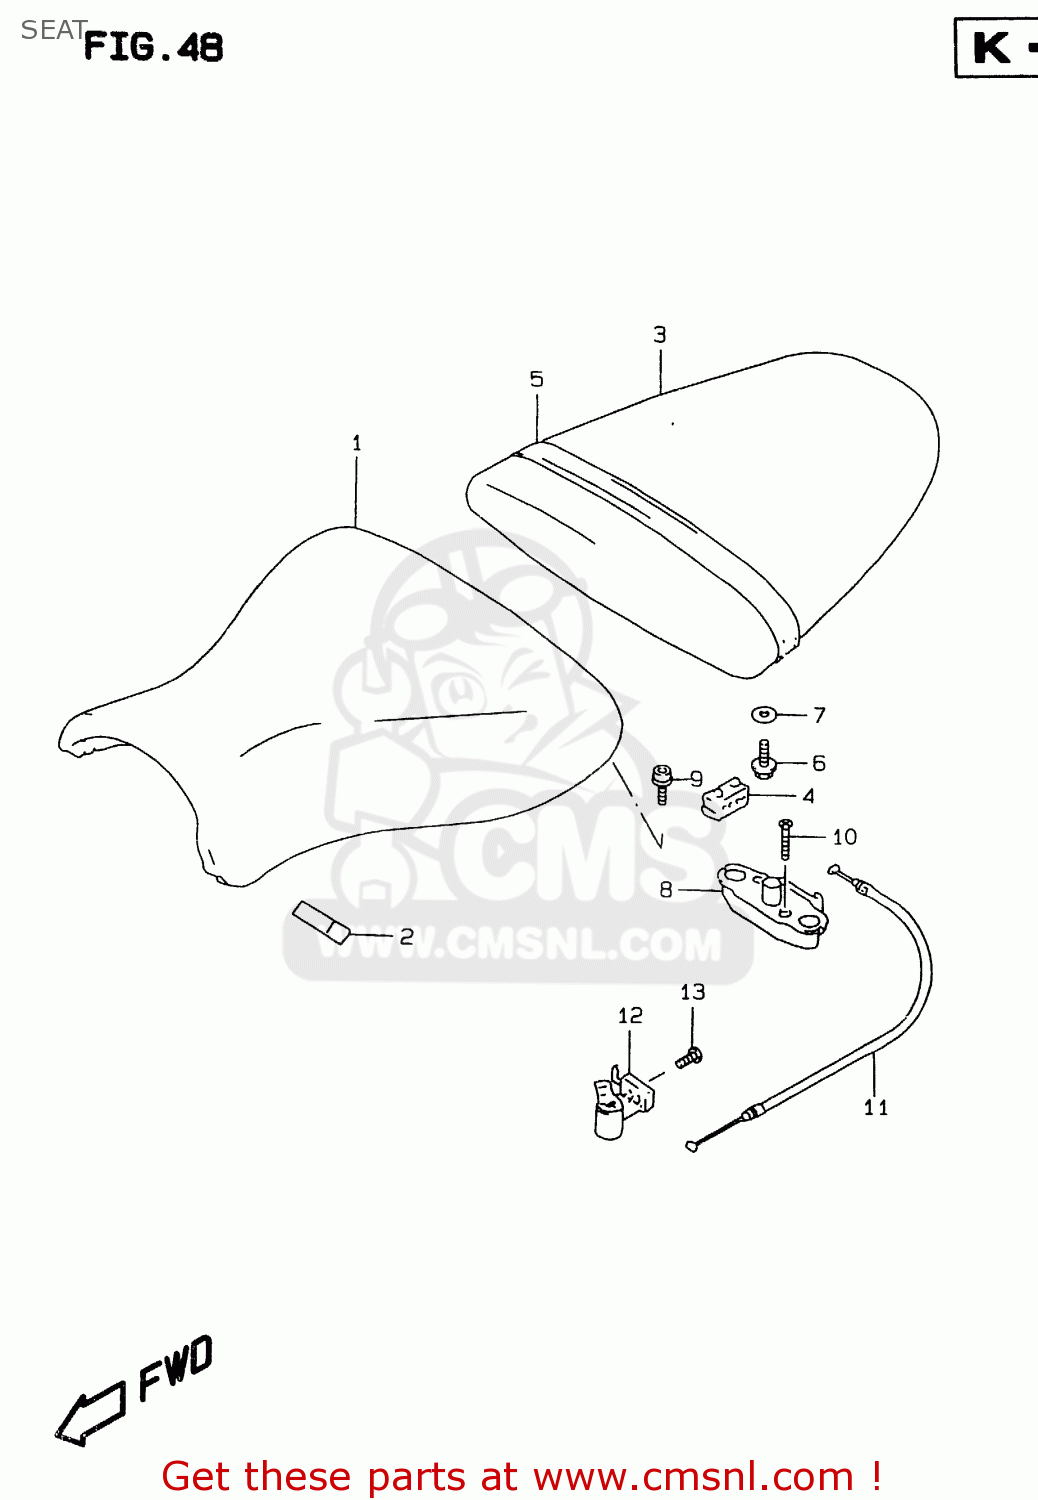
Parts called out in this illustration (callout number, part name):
1	SEAT ASSY(BLACK)
2	CUSHION,FR(20X40X15)
3	SEAT ASSY,PILLION
4	CUSHION,SEAT(40X20X15)
5	BAND,SEAT
6	BOLT
7	WASHER(6.5X20X1.6)
8	BRACKET,SEAT SUPPORT,RIGHT
9	BOLT(6X18)
10	SCREW
11	CABLE,SEAT LOCK
12	LOCK SET,SEAT
13	SCREW
